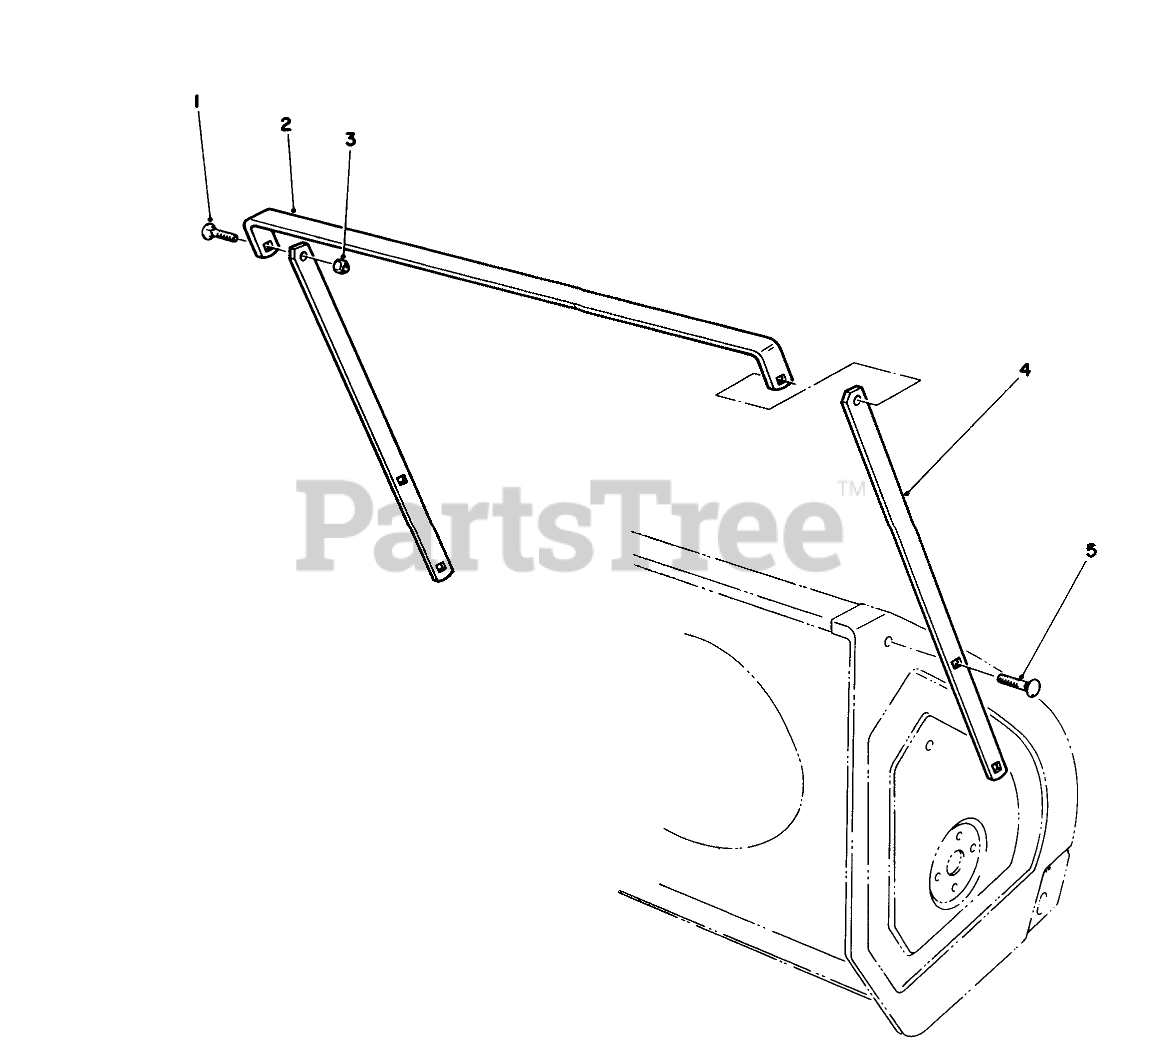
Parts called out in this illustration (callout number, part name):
1	SCREW-CARR
2	Breaker-Top (28")
3	NUT-LOCK, NI
4	Breaker-Side
5	BOLT-CARR
